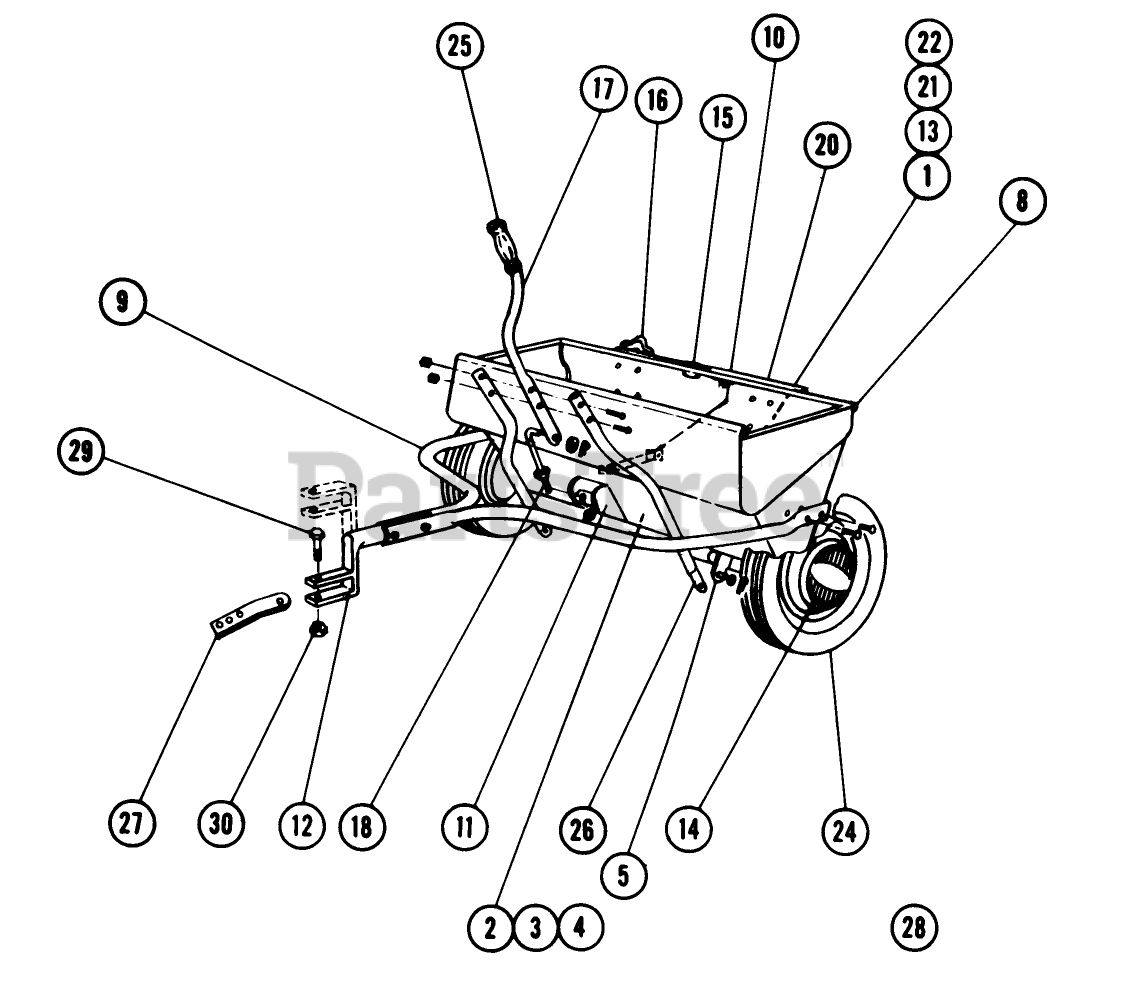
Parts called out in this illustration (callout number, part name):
1	Spring-Control Rod
2	Agitator-R.H.
3	Agitator-L.H.
4	Baffle
5	Ranger Shut-Off Bar
6	Shut Off Bar
7	Bearing Support Ass-y. with Bearing
8	Hopper
9	Hitch Brace
10	Brace-Hopper
11	Pivot-Bracket Ass-y.
12	Hitch
13	Housing-Control Ass-y. (Less Knob)
14	Hub Cap
15	Rate Indicator
16	Knob
17	Operating Lever with Grip
18	Pivot Link Rod
19	Hopper End Plate
20	Plate-Rate Control
21	Rod-Rate Control-R.H.
22	Rod-Rate Control-L.H.
23	Bearing
24	Wheel with Tire
25	Handle Grip
26	Shut Off Brace
29	Bolt-7/16-14 x 2 Hex.
30	Nut 7/16-14 Nylok
31	Tie Bar
